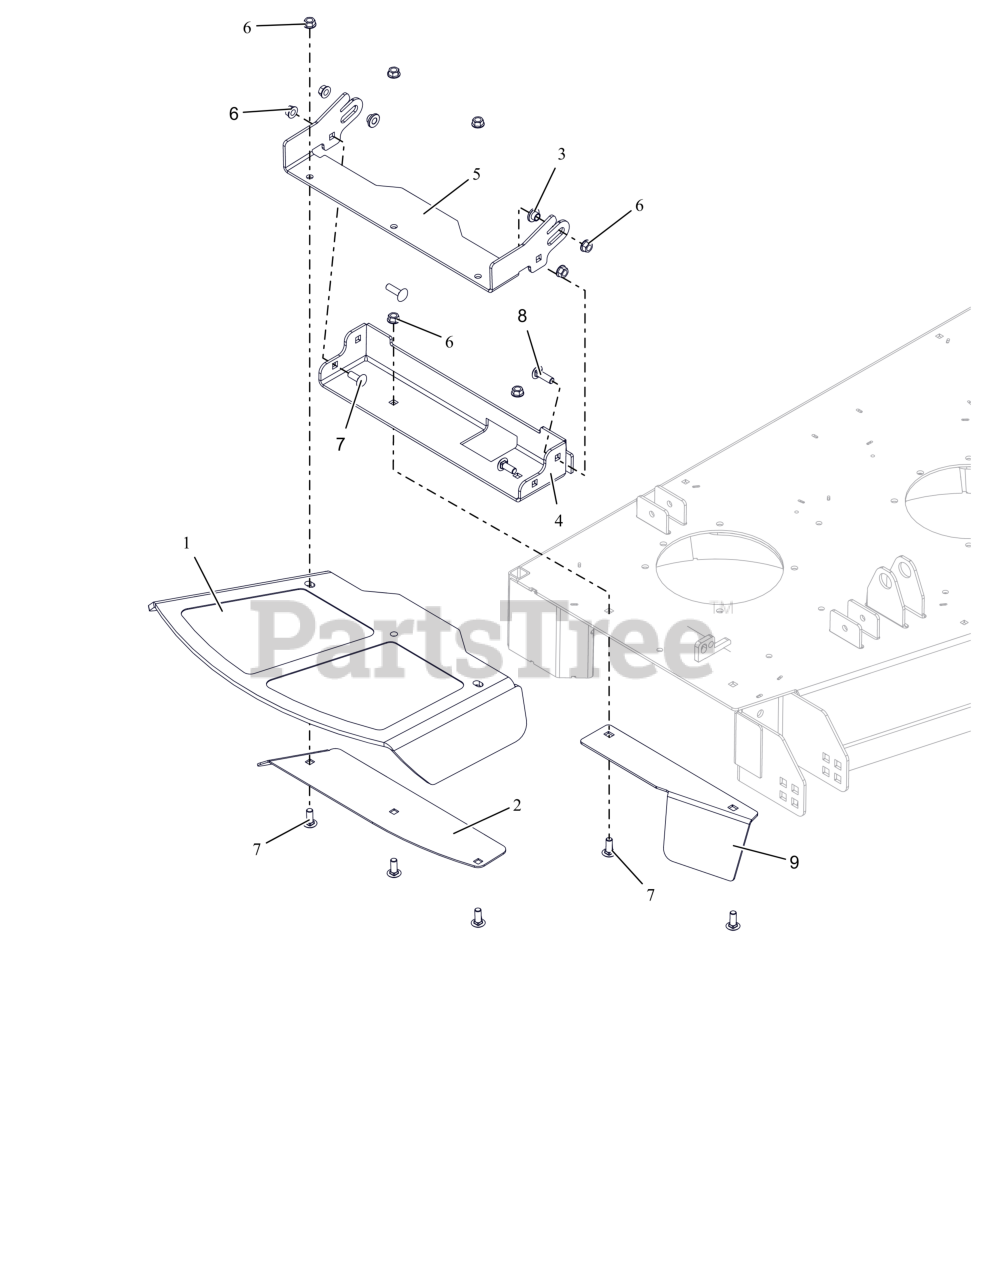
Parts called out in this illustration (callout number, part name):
1	CHUTE, FORMED RUBBER DISCHARGE
2	PLATE, 48-60" DISCH CHUTE CLAMP (BLACK)
3	BSHG-FLG .385X.500X.875X.406
4	KIT-DISCH CHUTE SM ORG W/DECAL
5	BRKT- CHUTE MTG
6	NUT-LK-CTR-FLG .375-16 GF ZCC
7	BLT,RHSSN .38-16X1.00 G5 ZCC
8	BLT,RHSSN .38-16X1.25 G5 ZCC
9	BRKT, DEFLECTOR (ORANGE)
